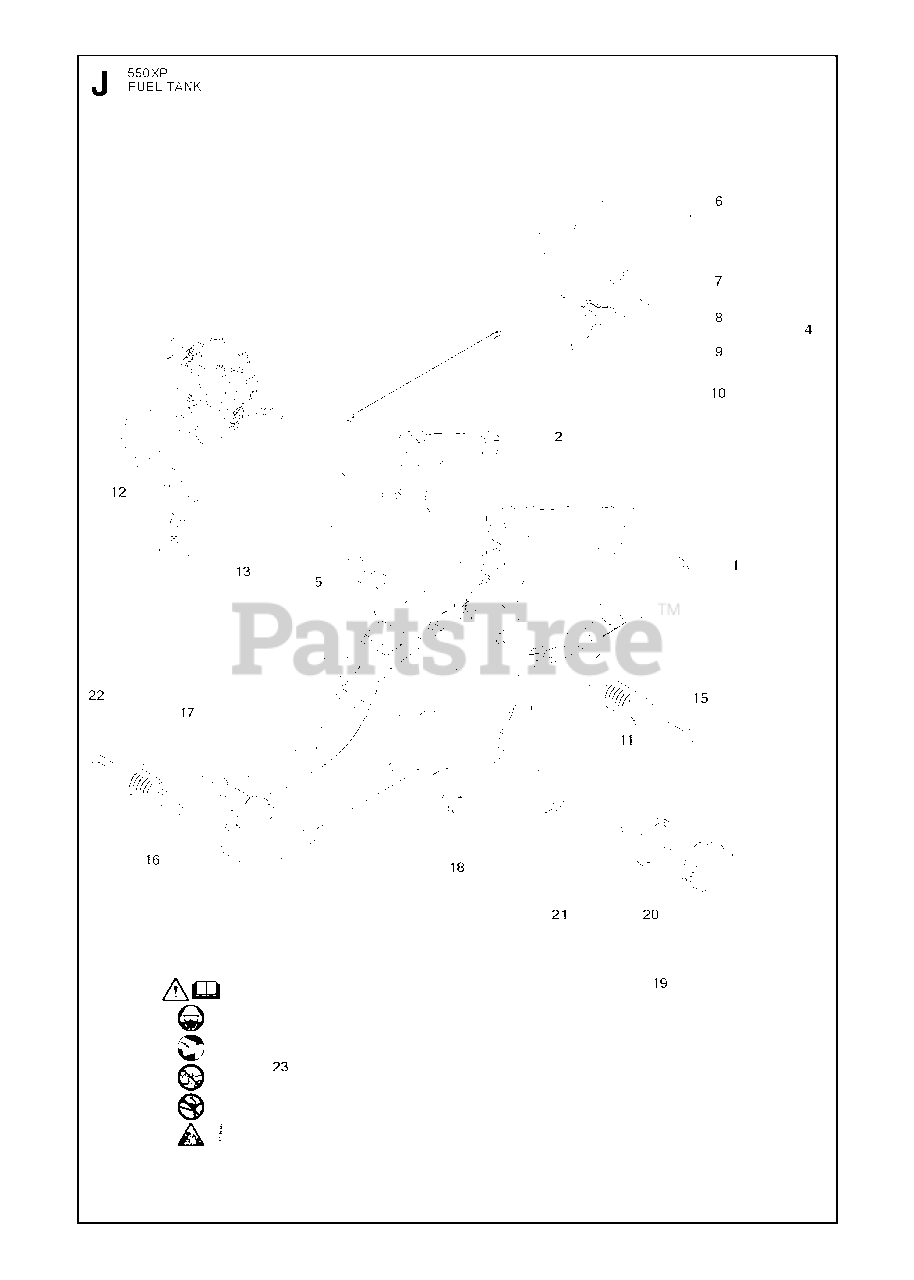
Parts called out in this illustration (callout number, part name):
2	HANDLE INSERT
4	FUEL TANK ASSY 50CC ORANGE
5	FUEL TANK VENT
6	THROTTLE LOCKOUT
7	SPRING
8	THROTTLE
9	PIN
10	THROTTLE CABLE ASSY
13	FUEL FILTER
15	ANTIVIBRATION ELEMENT
16	ANITVIBRATION ELEMENT
17	DEFLECTION LIMITER
18	LATERAL SUPPORT
19	TANK CAP ASSY
20	SEALING
21	TANK LOCK
23	DECAL
